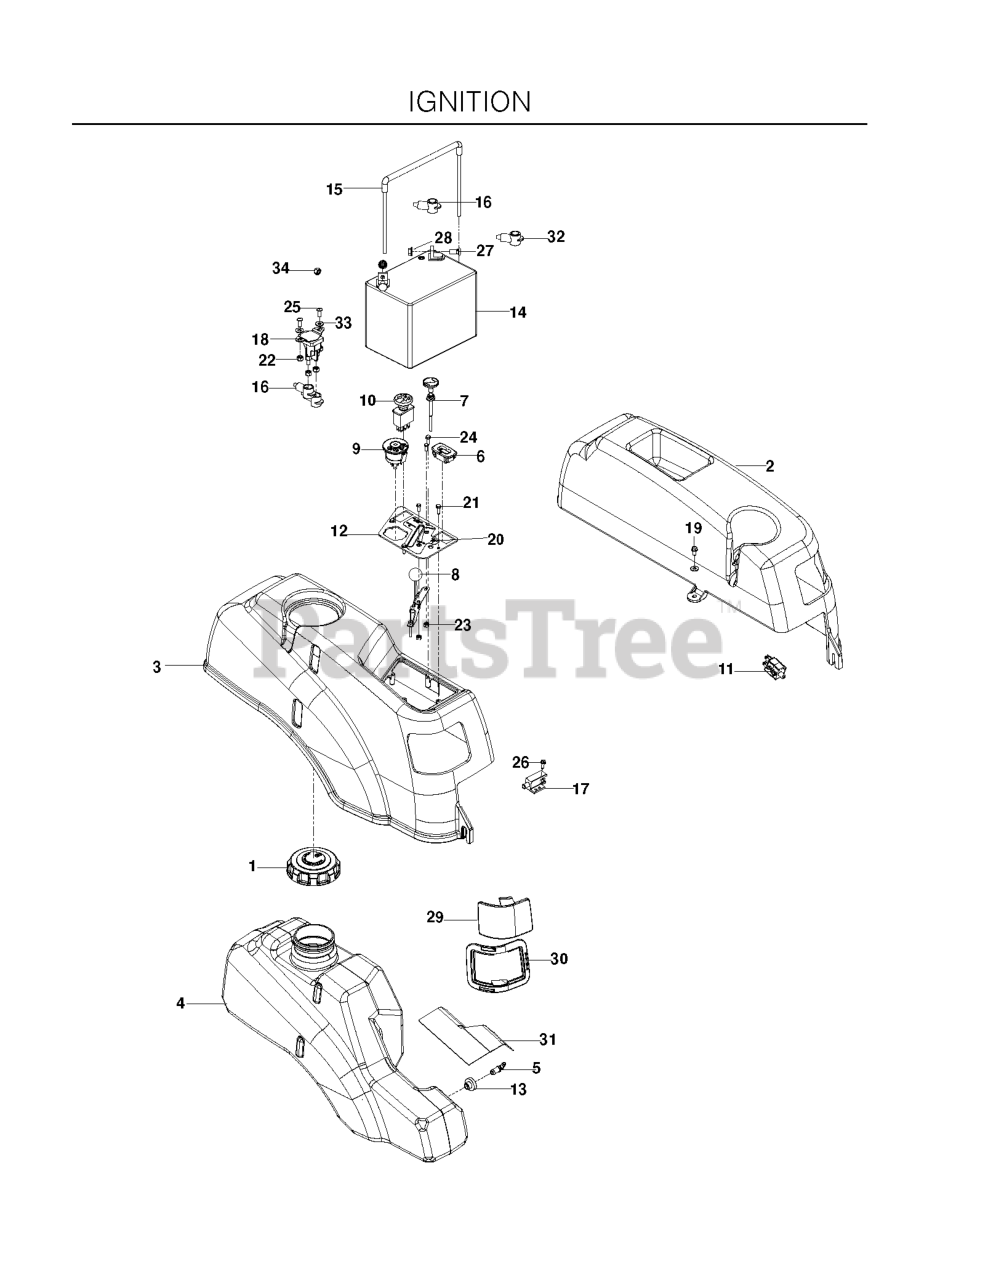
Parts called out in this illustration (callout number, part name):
1	FUEL CAP, HTC
2	FENDER, LT
3	RP.FENDER, RT
4	TANK, FUEL
5	STEM, FUEL TANK
6	HOUR METER
7	CHOKE CONTROL
8	THROTTLE CABLE
9	RP IGNITION SWITCH
10	RP.SWITCH, BLADE
11	SWITCH, BRAKE 3P
12	CONSOLE.PLATE.BLACK
13	RUBBER GROMMET
14	BATTERY, 12 V 330 AMP
15	BATTERY TIE DOWN ASSEMBLY
16	TERMINAL COVER-SM
17	SWITCH, INTERLOCK
19	BOLT 1/4-20 X 1/2 HWST
20	DECAL, IGNITION CONSOLE
21	HCS #10-24 X 1/2
22	NUT.1/4-20.HEX.NYLOC.ZD
23	NUT 10-24 NYLOC
24	SCR #10-12X3/4 HEX WAS HD ZD
25	SCR 1/4-20 X 5/8 BTN SKT HD ZD
26	SCREW #10 X 1/2 SELF TAPPING
27	BOLT 5/16C X 3/4" CARRIAGE
28	5/16-18 NYLOC FLANGE NUT
29	LENS, COLORED RIGHT
29	LENS, COLORED LEFT
30	RT HEADLIGHT RIM GREY
30	LEFT HEADLIGHT RIM GREY
31	SHIELD, HEAT
33	WASHER 1/4 INT TOOTH
34	JAM NUT 1/4C (2 2 PW01)
